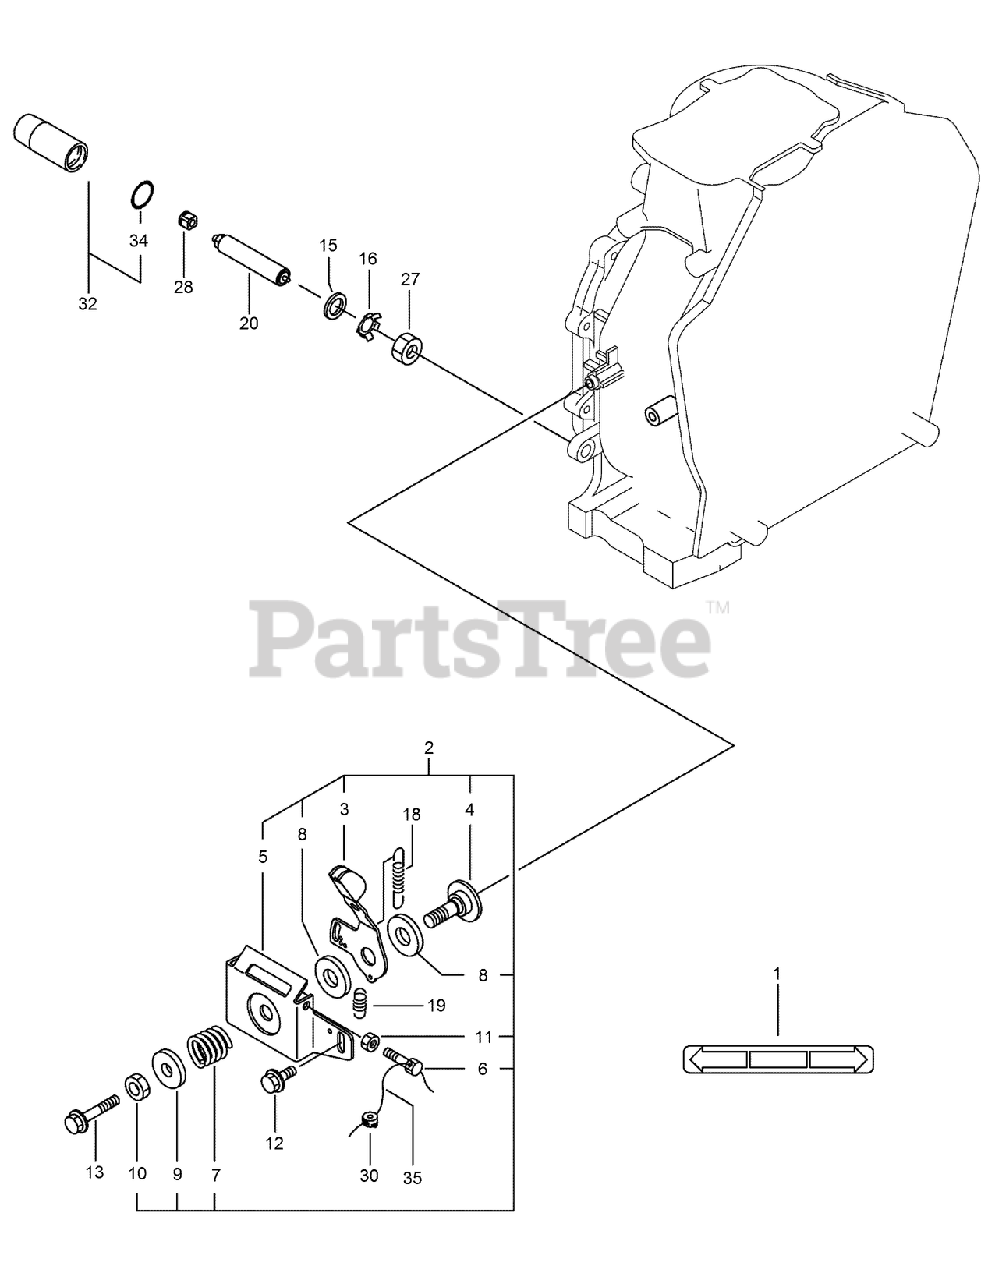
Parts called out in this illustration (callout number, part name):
1	LABEL-OPERATION
2	BRACKET ASM
3	BRACKET ASM
4	SHAFT-HANDLE
5	BRACKET-HANDLE
6	BOLT-ADJUSTING
7	SPRING-HANDLE
8	PLATE-FRICTION
9	WASHER
15	WASHER-PLAIN
18	SPRING-REGULATOR
19	SPRING-RETURN
20	LIMITER ASM
28	CAP-LIMITER
32	PROTECTOR ASM
34	O-RING
